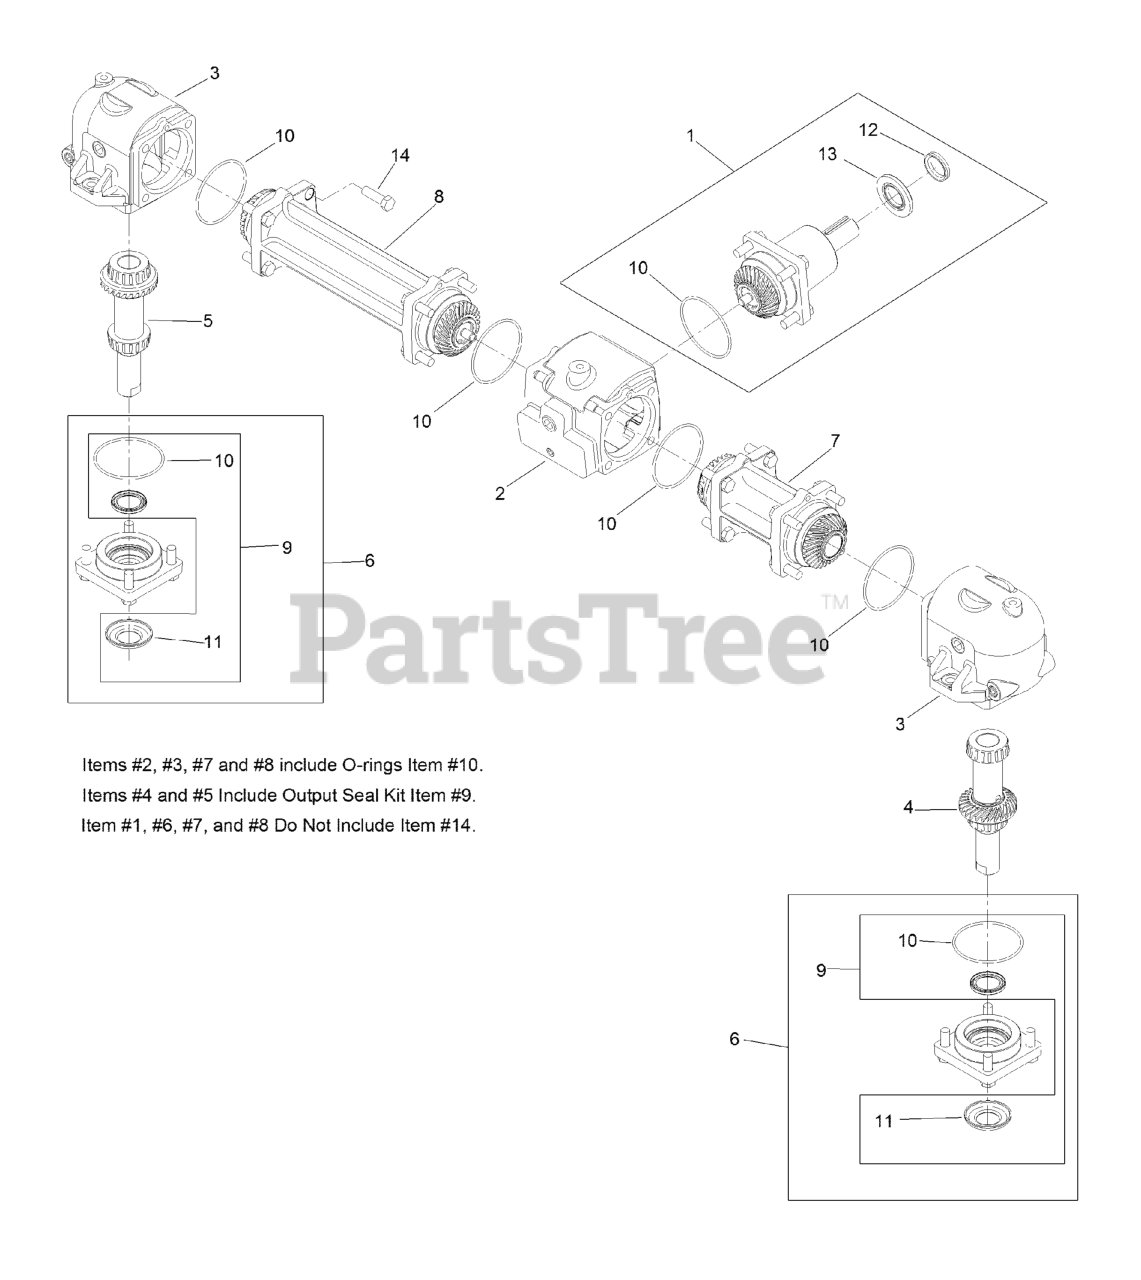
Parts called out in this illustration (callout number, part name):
1	INPUT PINION ASM
2	HOUSING-CENTER
3	HOUSING-END
4	LH OUTPUT SHAFT AND GEAR
5	RH OUTPUT SHAFT AND GEAR
6	CAP-OUTPUT
7	TUBE-CONNECTOR, SHORT
8	TUBE-CONNECTOR, LONG
9	OUTPUT SEAL KIT
10	SEAL-O-RING
11	WASHER-CUPPED
12	SEAL-V-RING
13	SEAL-INPUT
